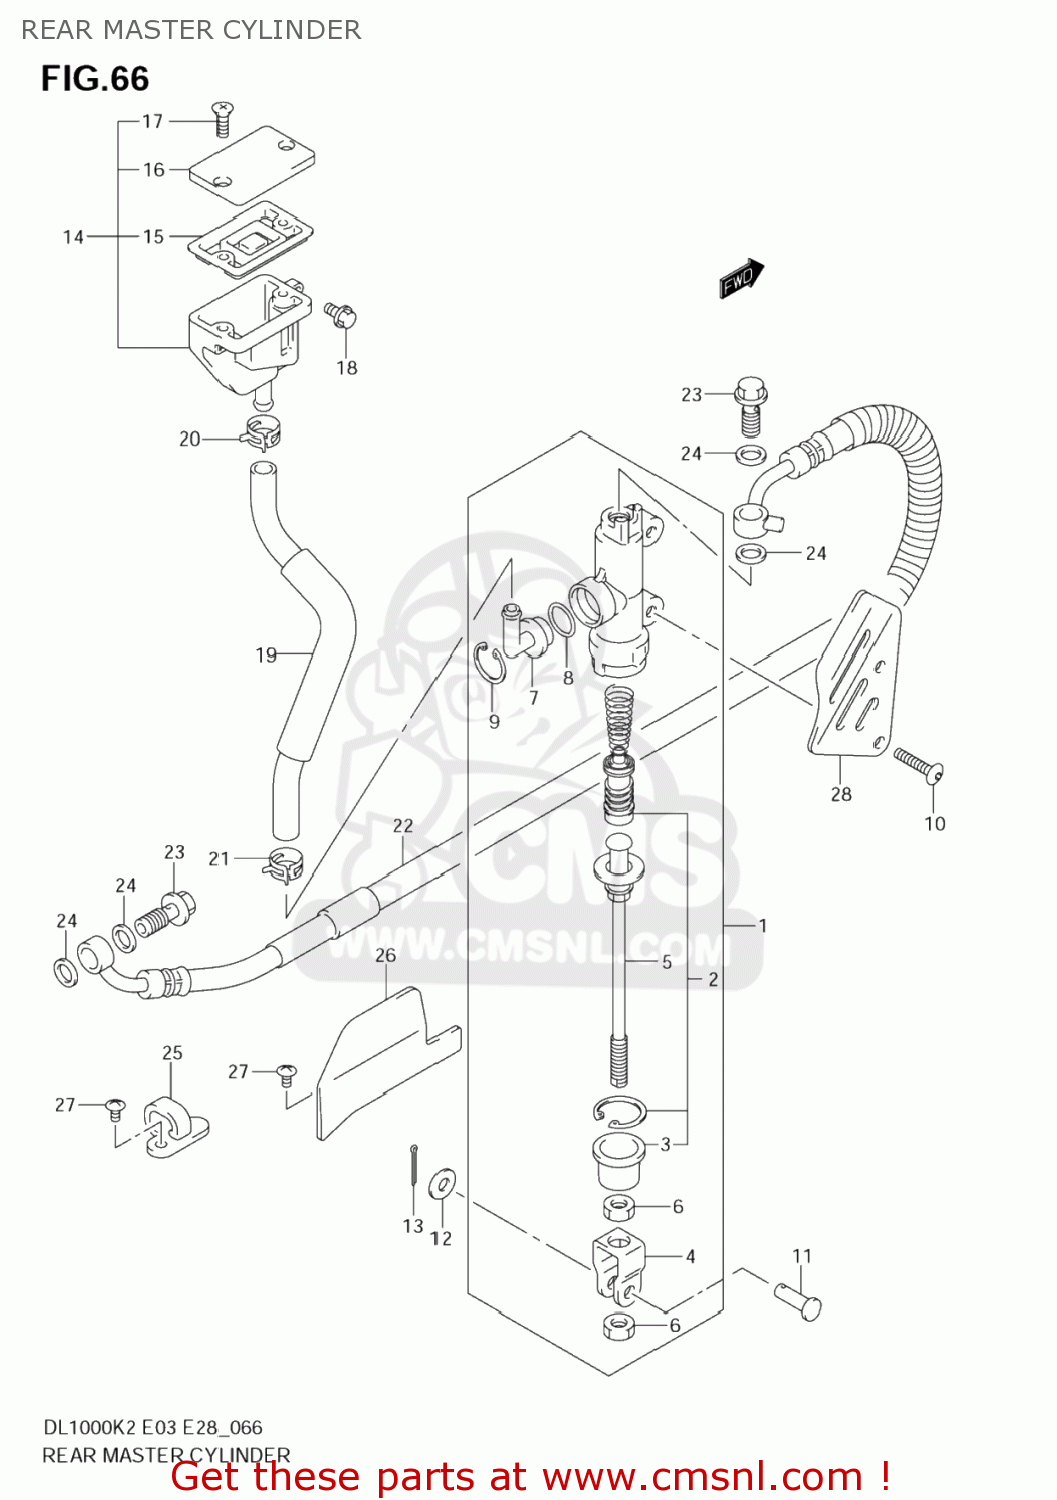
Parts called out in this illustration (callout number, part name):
1	CYLINDER ASSY,RR MASTER
2	PISTON/CUP SET
3	BOOT
4	YOKE
5	ROD,PUSH
6	NUT
7	CONNECTOR
8	O RING
9	CIRCLIP
10	SCREW(6X25)
11	PIN
12	WASHER
13	PIN
14	TANK ASSY,RR RESERVOIR
15	DIAPHRAGM
16	CAP
17	SCREW
18	BOLT
19	HOSE,RR RESERVOIR TANK
20	CLIP
21	CLIP
22	HOSE, REAR BRAKE
23	BOLT UNION
24	WASHER(10X15X1.5)
25	GUIDE,RR BRAKE
26	GUIDE,RR BRAKE HOSE FR
27	SCREW
28	COVER,RR MASTER CYLINDER
